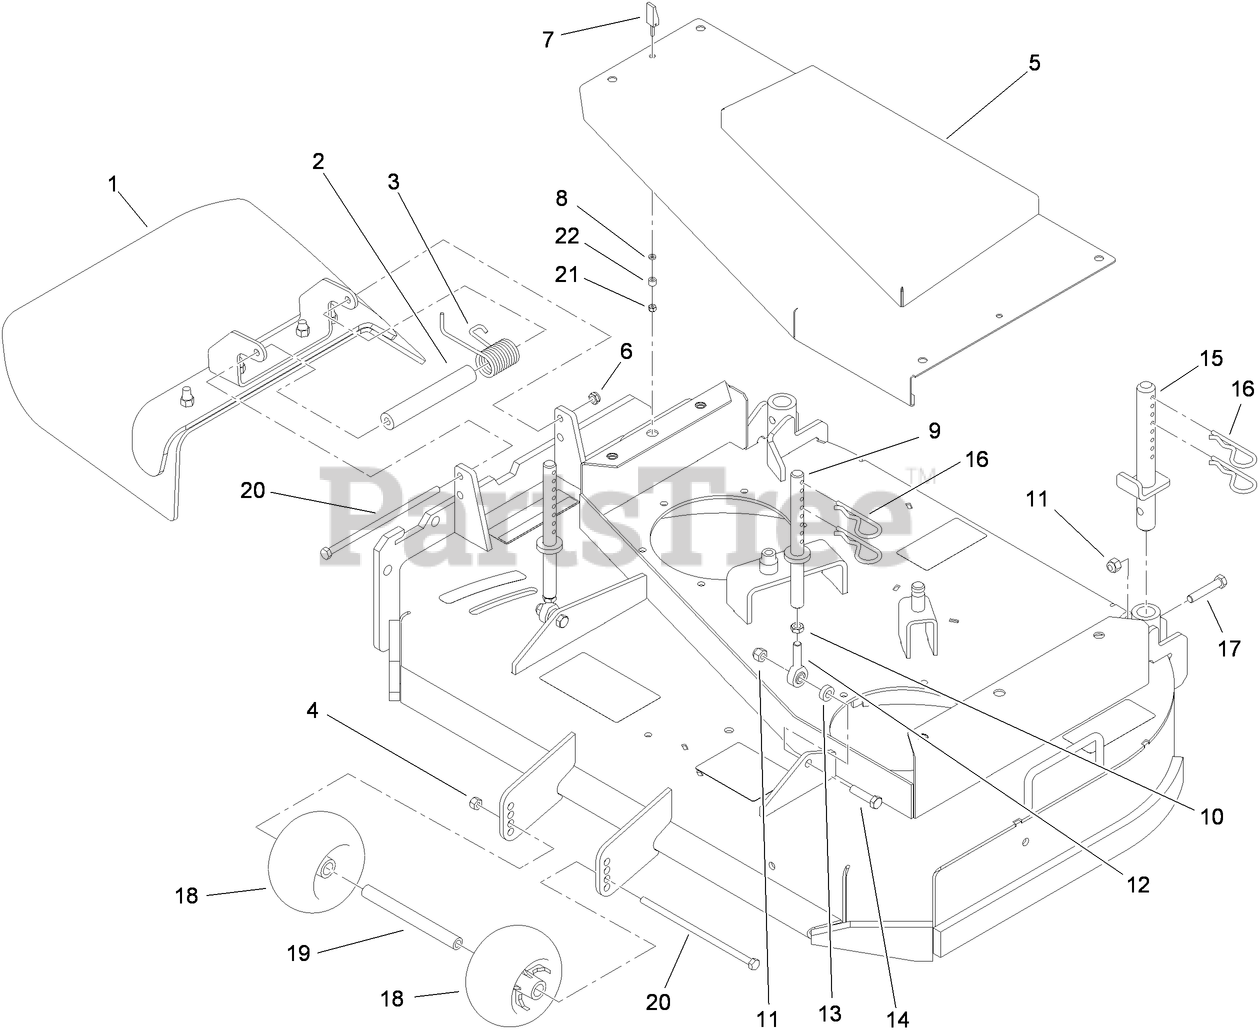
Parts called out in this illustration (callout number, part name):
1	DEFLECTOR ASM
2	SPACER
3	SPRING-TORSION
4	NUT-LOCK, NI
5	COVER ASM
6	NUT-LOCK, NI
7	HANDLE-LATCH, SWELL
8	WASHER
9	FRONT PIN ASM
10	NUT-HJ
11	NUT-LOCK, NI
12	BALLJOINT
13	SPACER
14	SCREW-HH
15	REAR PIN ASM
16	PIN-HAIR
17	SCREW-HH
18	ROLLER-SCALP, ANTI
19	SPACER-WHEEL
20	SCREW-HH
21	NUT-LOCK, HH
22	BUSHING-LATCH, SWELL
